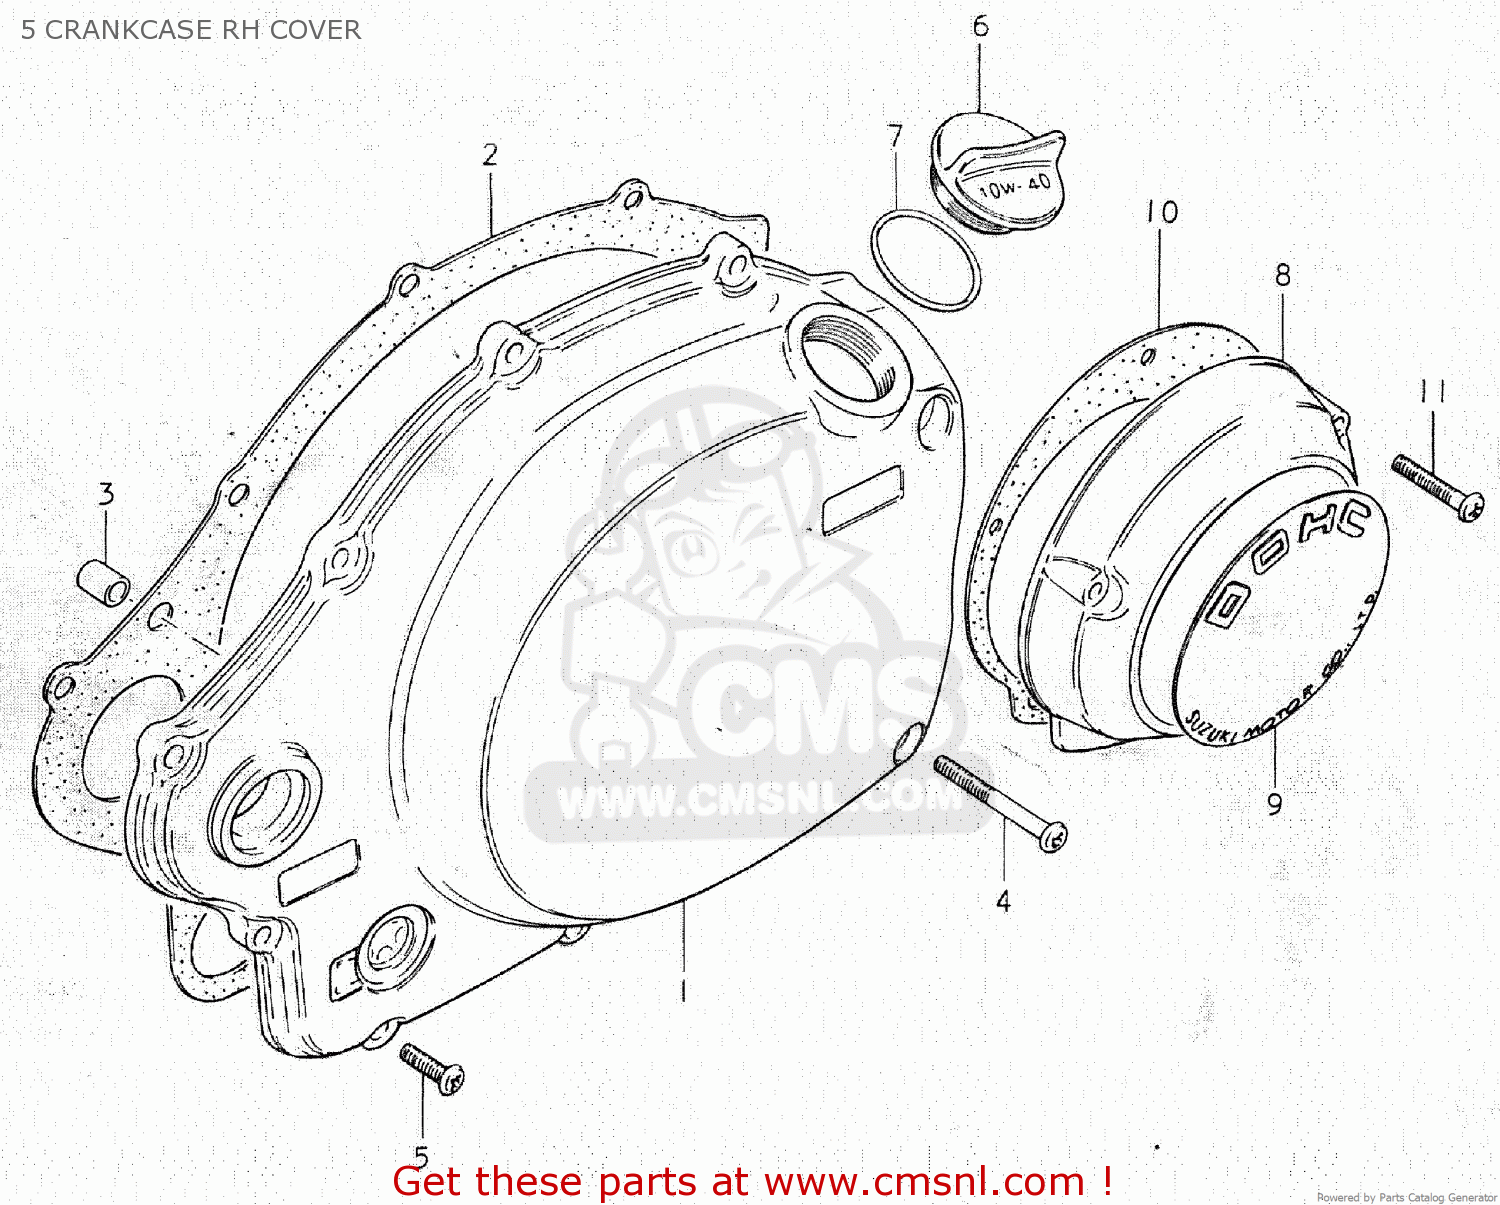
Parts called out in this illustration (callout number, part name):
1	COVER,CLUTCH
2	GASKET,CLUTCH COVER (MCA)
3	PIN
4	SCREW
5	SCREW
6	CAP
7	O RING(D:2.2,ID:32)
8	COVER,CONTACT BREAKER
9	EMBLEM
10	GASKET,CONTACT BREAKER COVER (NAS)
11	SCREW
